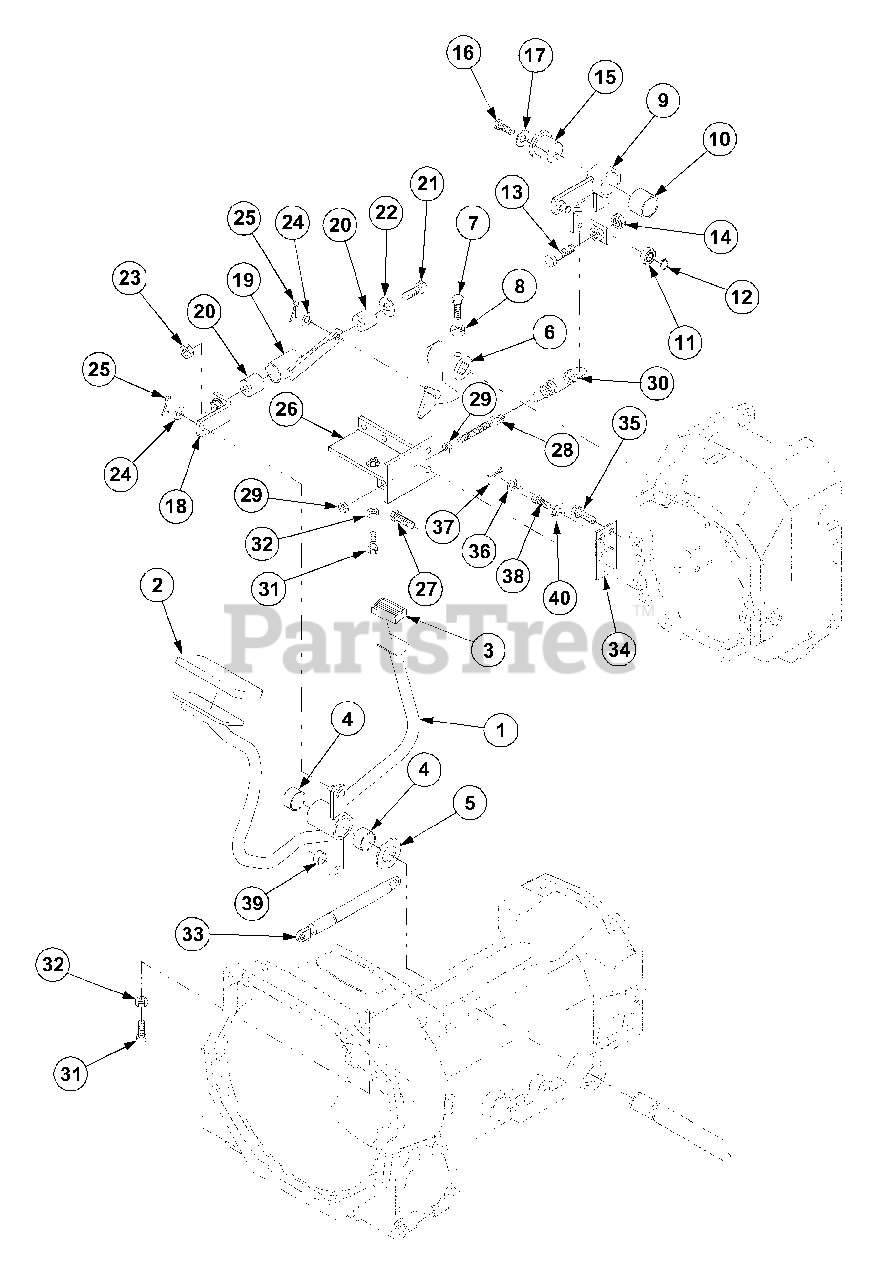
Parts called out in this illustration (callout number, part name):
6	Arm, Trunnion
9	Arm, Neutral - Before S/N 15867
9	Arm, Neutral - S/N 15867 & After
11	Bearing, Ball
12	C-Ring
13	Bolt - Before S/N 15867
13	Bolt - S/N 15867 & After
14	Nut - Before S/N 15867
14	Nut - S/N 15867 & After
15	Shaft, Holder
16	Bolt 7T, Reamer
25	Pin, Split
27	Bolt, w/Washer
35	Bolt, w/Washer
37	Pin, Split
40	Washer, Spring
